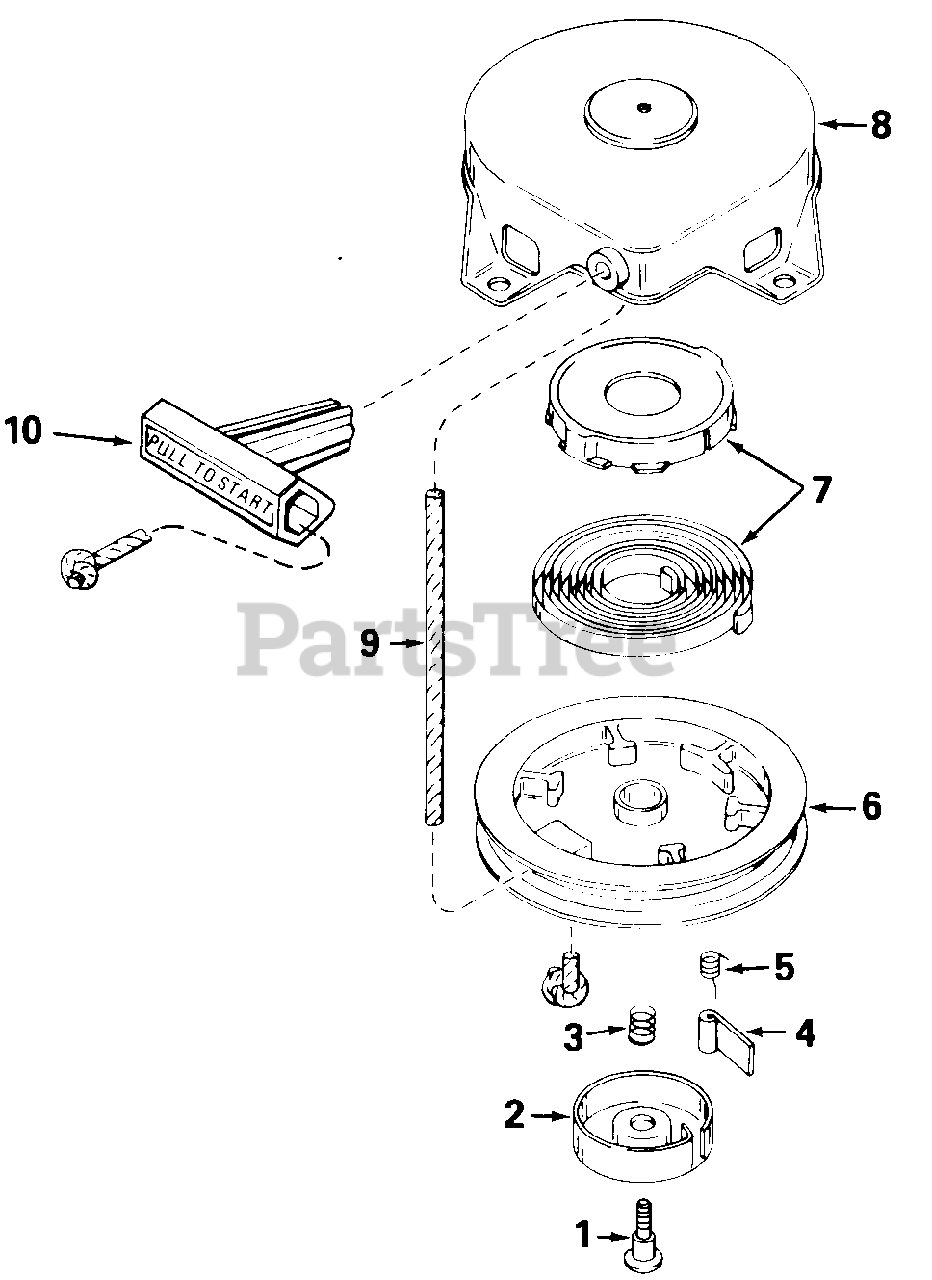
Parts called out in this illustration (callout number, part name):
1	Screw, Retainer
2	Retainer, R.H.
3	Spring, Brake
4	Dog, Starter
5	Spring, R.H. Dog
7	Spring & Keeper Ass'y.
8	Housing Ass'y., Starter
9	Rope, Starter
10	Handle Ass'y. Starter
